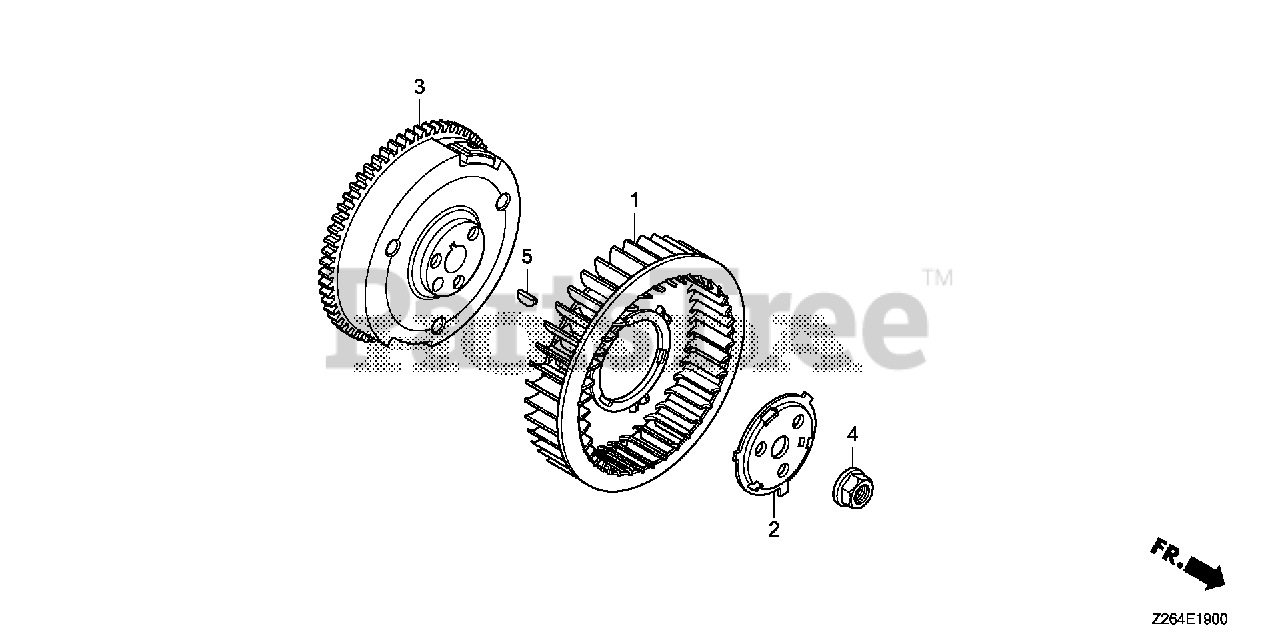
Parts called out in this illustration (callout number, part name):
1	FAN, COOLING
2	PLATE, COOLING FAN SETTING
4	NUT, SPECIAL (20MM)
5	KEY, SPECIAL WOODRUFF (25X18)
